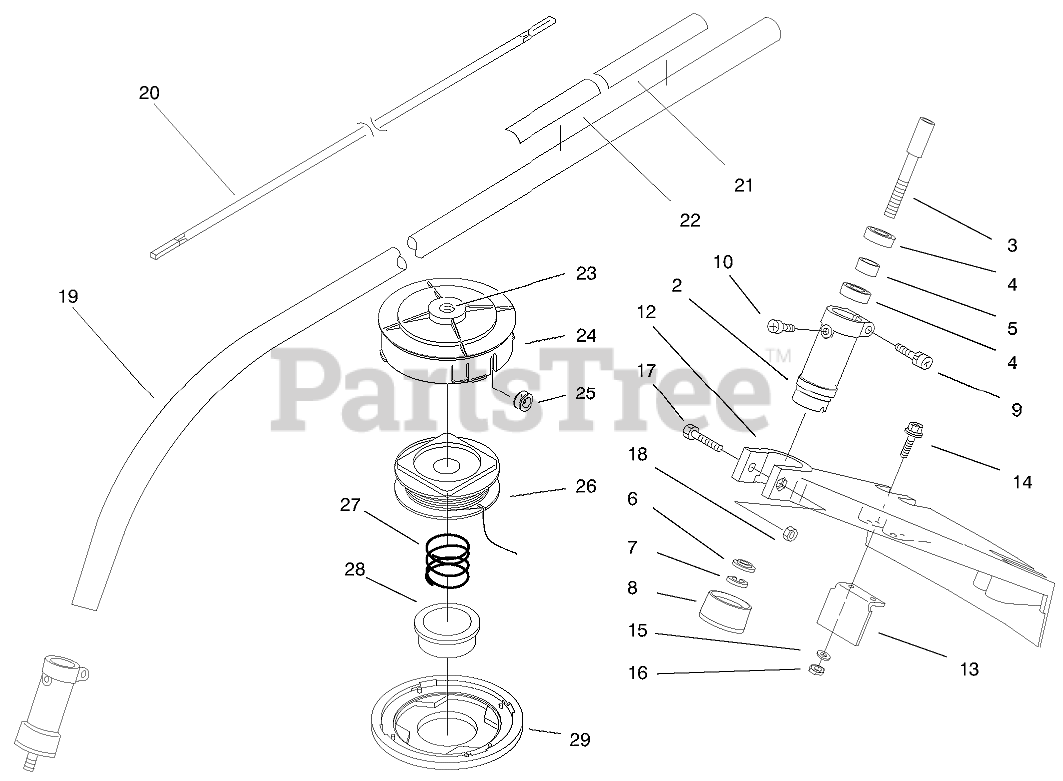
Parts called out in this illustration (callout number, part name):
2	BEARING HEAD
3	SHAFT
4	BEARING
5	SPACER
6	INNER CAP
7	WASHER - SPRING
8	OUTER CAP
9	SCREW
10	SCREW
12	SHIELD
13	STRING CUTTER
14	SCREW
15	WASHER - SPRING
16	NUT M5
17	SCREW
19	Driveshaft Tube Asm (Incl. Ref. # 22)
20	DRIVE SHAFT-FLEXIBLE
21	DECAL - TORO
22	DECAL - CAUTION
23	BOLT (UA-1006)
24	HOUSING
25	EYELET
26	SPOOL W/LINE (LH)
27	SPRING
28	BUTTON
29	COVER (SN-348L)
